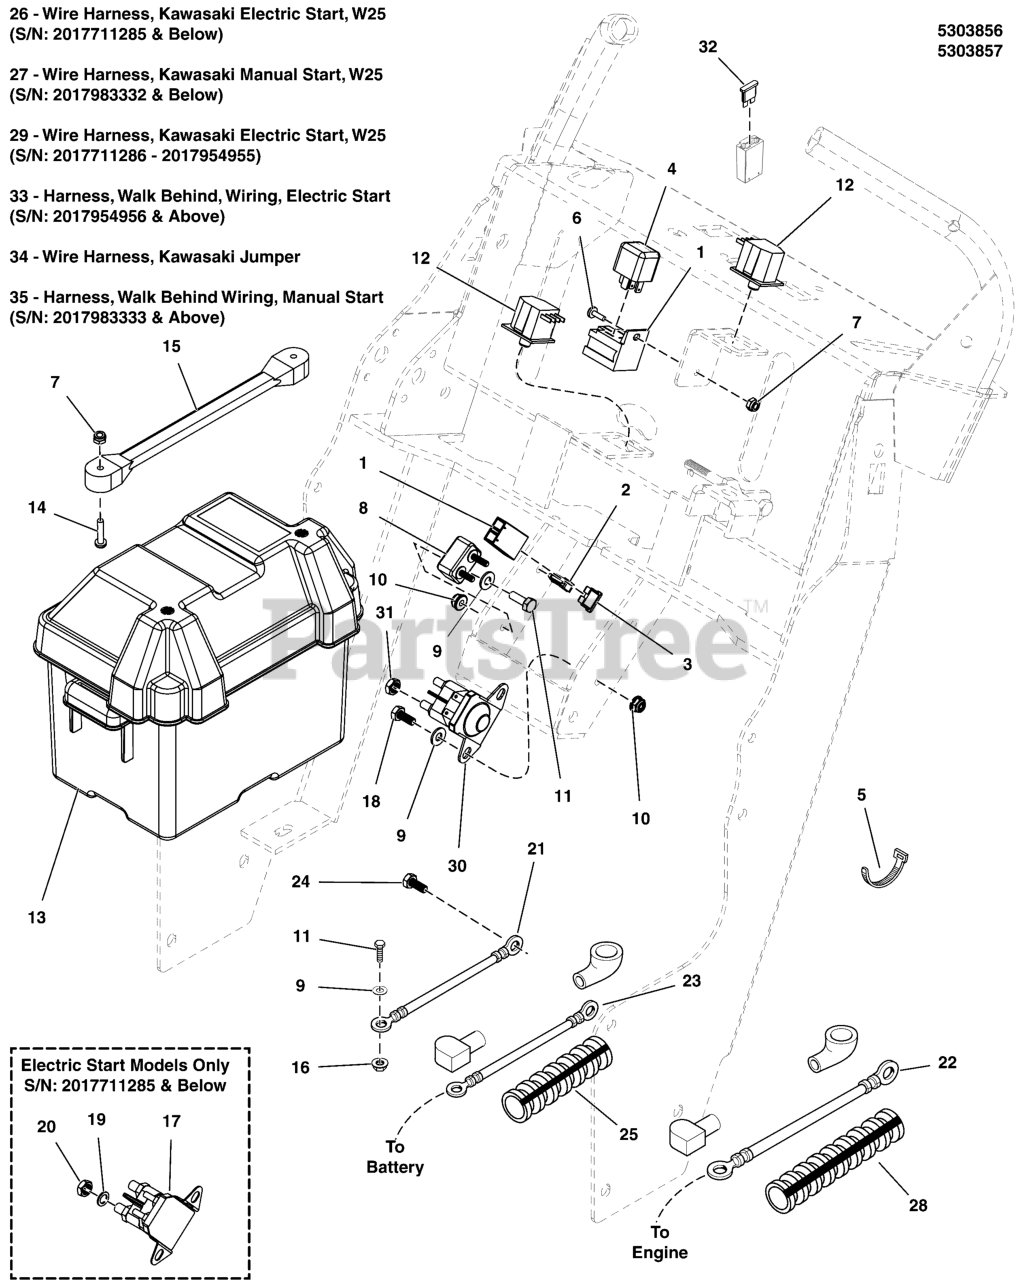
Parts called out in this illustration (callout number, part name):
1	SEE WIRE HARNESS PART NUMBER
2	FIR TREE MOUNT, PACKARD
3	FUSE, ATO-15 (15 AMP)(SV)
4	RELAY, 12 VOLT, 40 AMP
5	TIE, SELF-LOCKING, 12"
6	SCREW, #10-24 X 1/2" ROUND PHILLIPS
7	NUT, Hex, Nylon Lock, #10-24
8	BREAKER-CIRCUIT 12VOLT 20AMPS W/TAB
9	WASHER, 1/4 SAE
10	NUT, 1/4-20 Hex Nylock Flange
11	BOLT, 1/4"-20 X 3/4" GD5 YZ
12	SWITCH, PLUNGER, NO/NC SNAP-IN, LOW PROFILE
13	BATTERY BOX, W/ DRAIN HOLE
14	SCREW, #10-24 X 1 RS, CZ
15	STRAP, RUBBER
16	NUT, 1/4-20 HEX SERR. FLANGE
17	SOLENOID-4 POLE 12 VOLT DC (TROMBETTA)
18	HHCS, 1/4-20 X 0.625, GR5, ZINC/CLEAR
19	WASHER, Light Lock, 5/16
20	NUT, Hex Jam, 5/16-24
21	BATTERY CABLE, NEG, 22, 1/4-5/16
22	BATTERY CABLE, POS, 22, 1/4-5/16
23	BATTERY CABLE, POS, 15, 1/4-5/16
24	BOLT, M8-1.25 X 20 MM GD 8.8
25	WIRE LOOM, 3/8 ID X 10 IN
26	WIRE HARNESS, KAWI ELEC START, SW25
27	WIRE HARNESS, KAWI MANUAL START, SW25
28	WIRE LOOM, 3/8 ID X 16 IN
29	WIRE HARNESS, W25, KAWI ELECTRIC
30	SOLENOID, STD-BRACKET, 2-SPADE
31	NUT,1/4-20,KEPS,CONICAL WSHR,ZC/CL
32	FUSE, ATO-20 (20 AMP)(SV)
33	HARNESS, WALK BEHIND, WIRING
34	WIRE HARNESS, JUMPER, KAWI
35	HARNESS, MANUAL START WALK WIRING
